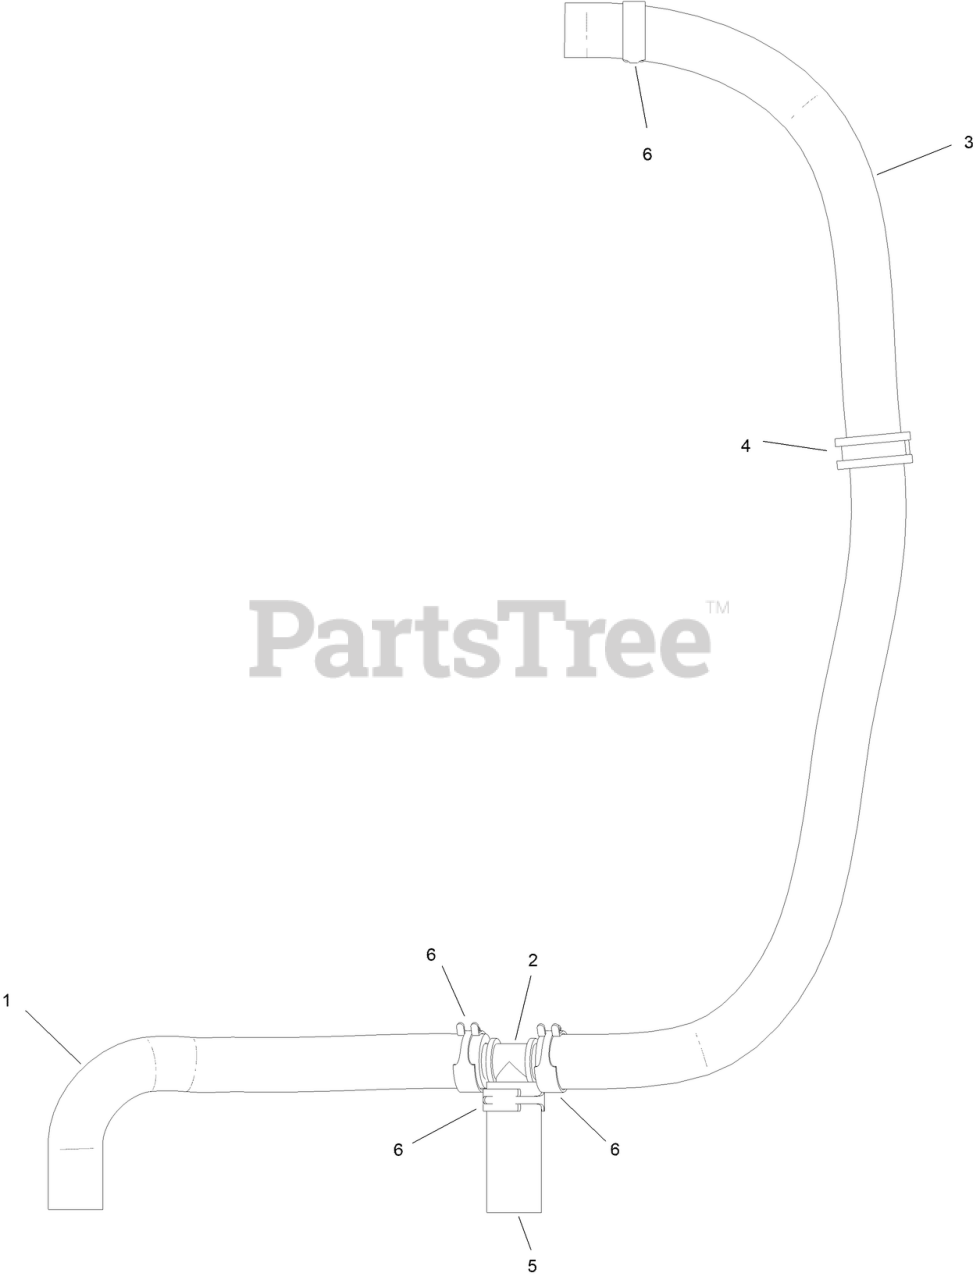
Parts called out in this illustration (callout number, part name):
1	HOSE-HYDRAULIC
2	FITTING TEE
3	HYDRAULIC HOSE
4	R-CLAMP
5	HYDRAULIC HOSE
6	HOSE CLAMP
